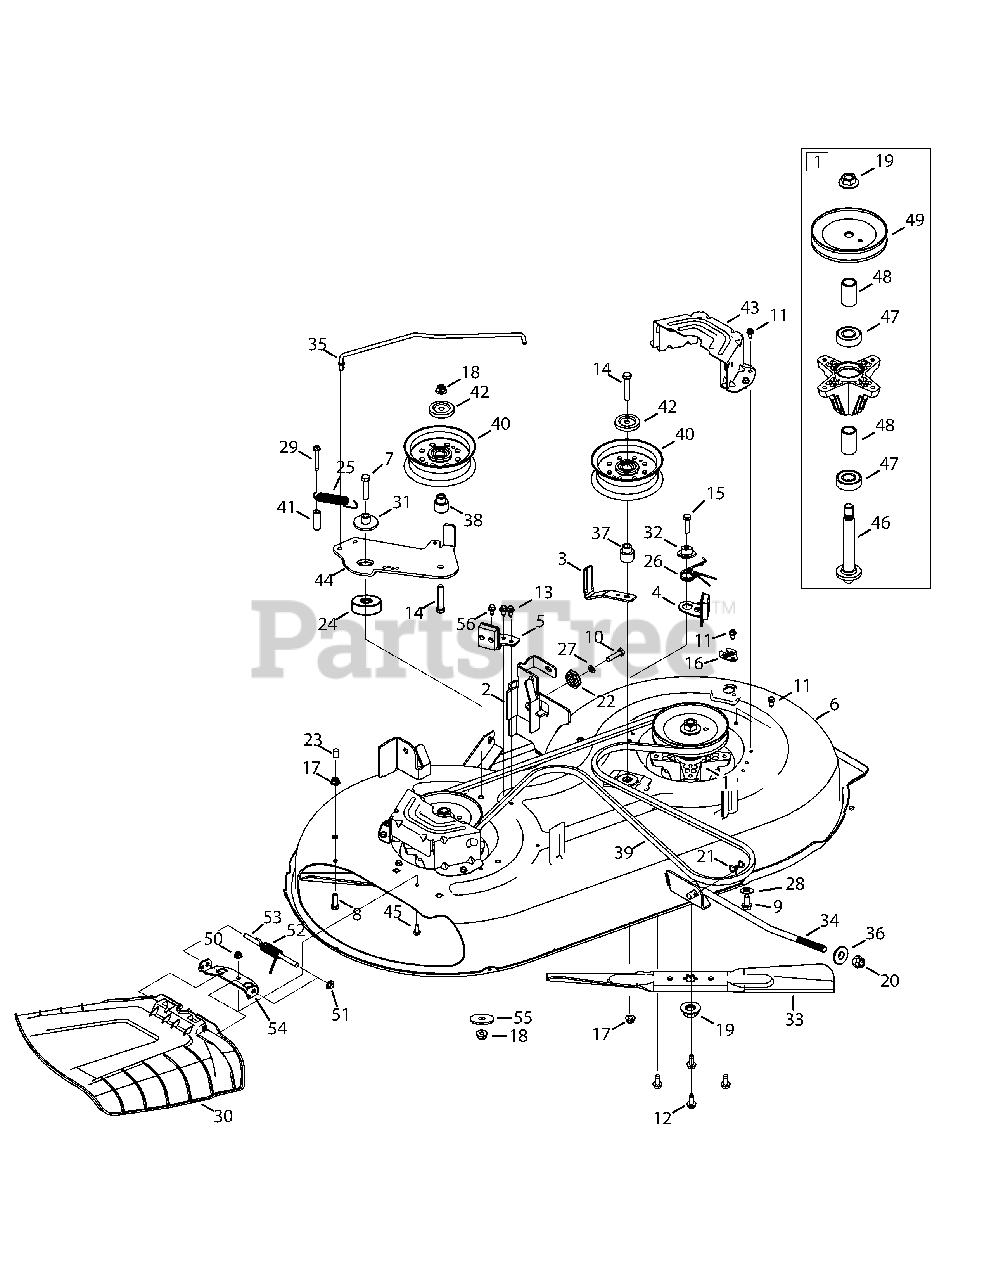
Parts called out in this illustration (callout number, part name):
1	Spindle Ass’y, Pulley, 6.2 Dia
2	Bracket Ass’y, Deck, Hanger LH
3	Belt Keeper
4	Brake Assembly, Deck, LH
5	Brake Assembly, Deck, RH
6	Deck, 42"
7	Hex Screw, 3/8-16 x 1.75
8	Hex Cap Screw, 5/16-18 x 1.00
9	Screw, Self-tapping, 5/16-18, .750
10	Hex Screw, 5/16-18, 1.25, Gr5, Std
11	Screw, Self-tapping, 1/4-20, 0.500
12	Screw, 5/16-18 x 0.750
13	Screw, M6-1 x .625
14	Hex Screw, 3/8-16, 2.00, Gr8, Std
15	Hex cap Screw, 5/16-18 x 1.25
16	Deck Wash Plug
17	Nut, Flange Lock, 5/16-18, Grf
18	Nut, Flange Lock, 3/8-16, Grf
19	Nut, Flange, 5/8-18
20	Flange Lock Nut, 1/2-13
21	Bow-Tie Cotter Pin
22	Gear, Deck, Adjustment
23	Cap, .290 x .500
24	Spacer, .385 x 1.75 x .585
25	Extension Spring, .750 X 4.77
26	Torsion Spring, LH
27	Washer, Lock, 5/16, Regular Duty
28	Flat Washer, .406 x .875 x .059
29	Screw, Self Tapping, 1/4-20, 1.50
30	Chute Deflector Assembly
31	Shoulder Spacer, .970 x .190
32	Shoulder Spacer, .75 x .145
33	Blade, Cut, 21.23" 2-In-1
34	Rod, Lift, Deck, Frt, 12.7
36	Deck Lift Pivot Cup
37	Shoulder Spacer, Idler
38	Shoulder Spacer, Pivot Idler
39	Belt, V Type, A Sec X 96.5
40	Pulley, Idler, 4.50"Dia
41	Spacer, .260 x .375 x 1.030
42	Pulley Cap
43	Deck Belt Cover, 42
44	Deck Idler Bracket
45	Hex Cap Screw, 1/4-20 x .62
46	Shift, Spindle, 6.11.
47	Bearing, Ball, .787id x 1.85 Odx.551
48	Spacer, .792 x 1.060 x 1.860
49	Pulley, Deck, 5.4 Dia
50	Nut, Flange Lock, 1/4-20, Nylon
51	Push Cap
52	Spring, Torsion, .440 ID x 1.75
55	Flat Washer, .406 x 1.50 x .105
56	Shoulder Screw, 1/4-20
